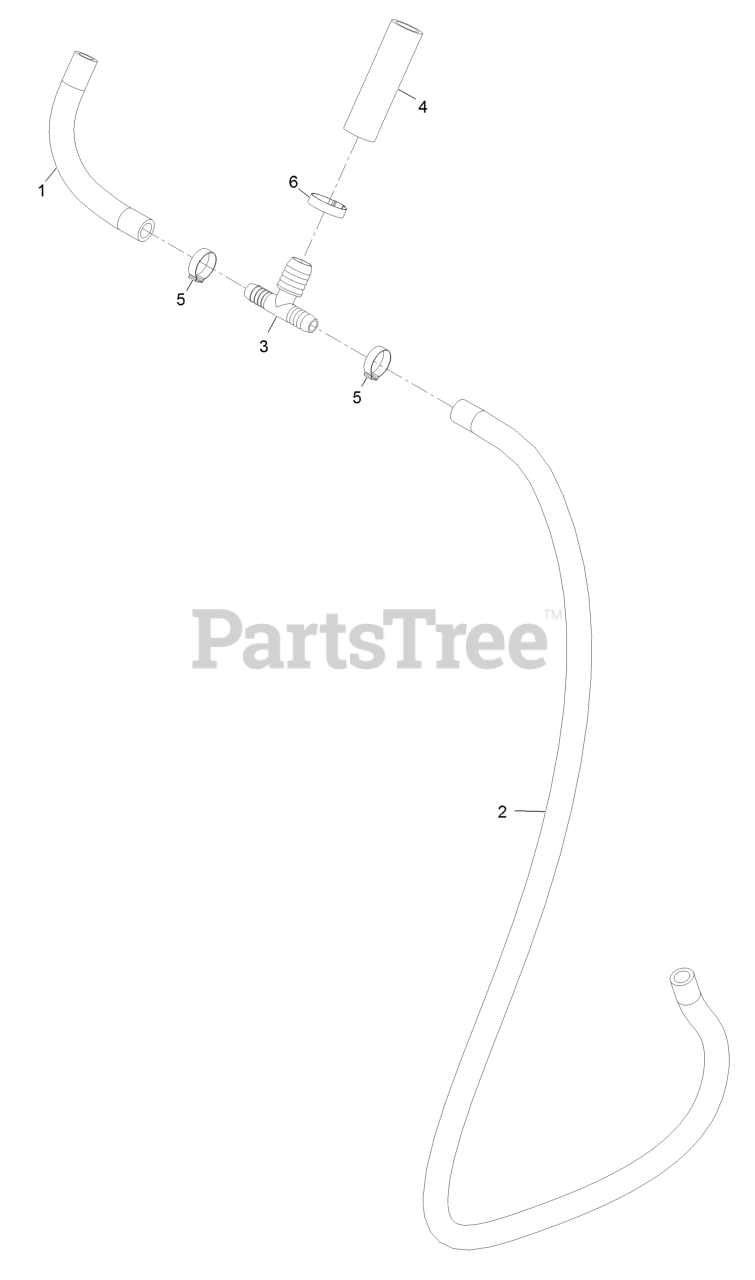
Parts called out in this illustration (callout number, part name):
1	HOSE-WATER
2	HOSE-WATER
3	FITTING-TEE
4	HOSE-WATER
